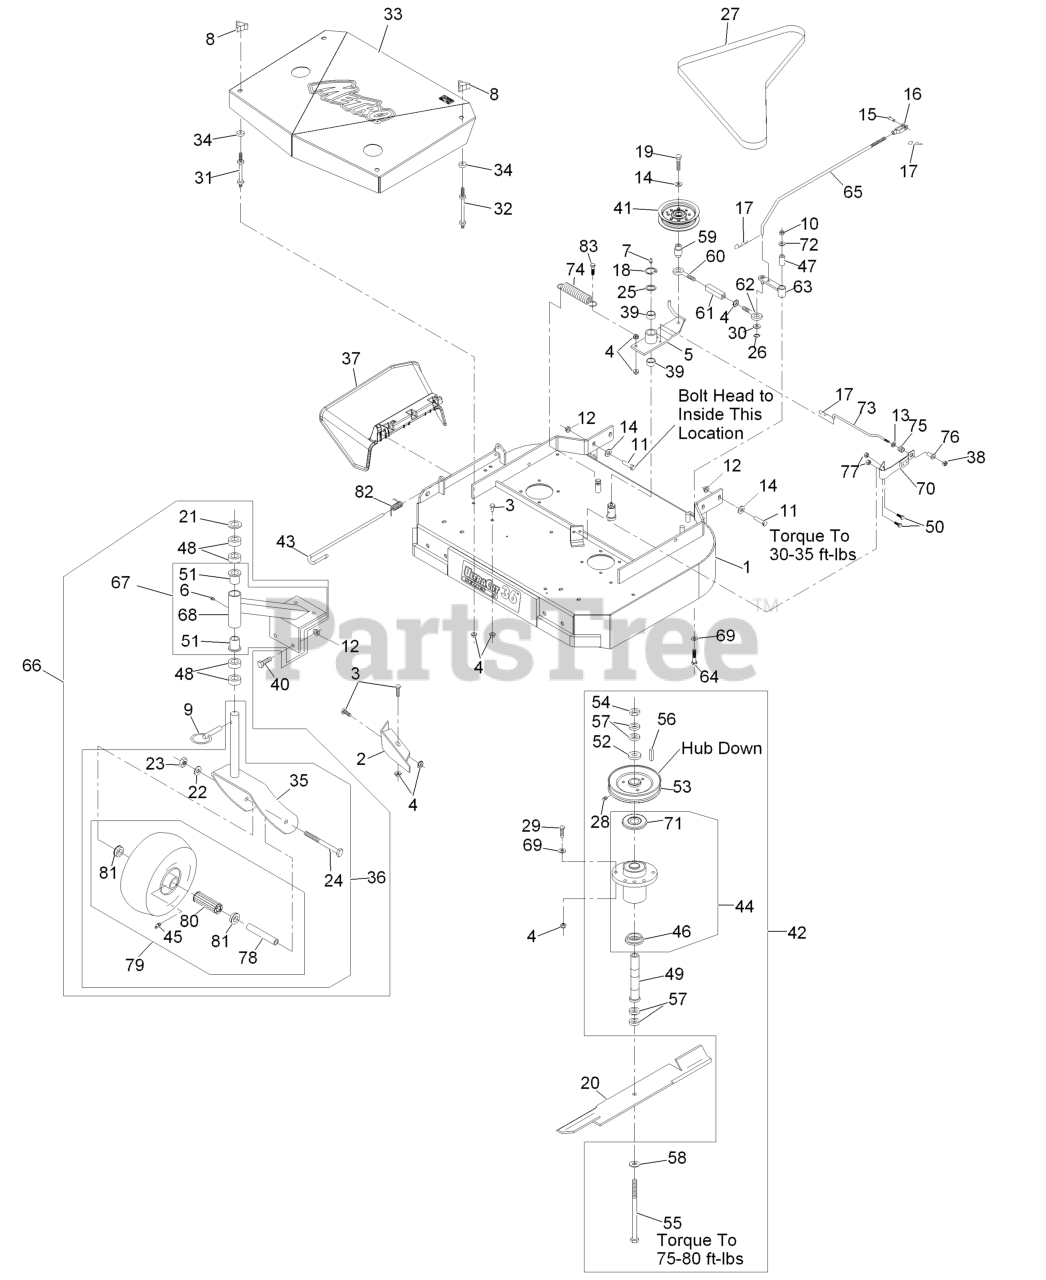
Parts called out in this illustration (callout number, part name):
1	ASM,DECK 36 RIGID
2	BAFFLE-DOGLEG
3	SCREW-HH
5	IDLER ARM ASM
6	FITTING-GREASE
7	FITTING-GREASE
8	KNOB-3 PRONG
10	NUT-LOCK, NI
11	SCREW-HH
12	NUT-HHF, WHIZ
13	RING-PUSH ON
14	WASHER-BELLEVILLE
15	PIN-CLEVIS
16	YOKE-ADJUSTABLE
17	PIN-COTTER
18	RING-RETAINING, EXT
19	SCREW-HH
21	WASHER-FLAT
22	WASHER-LOCK
23	NUT-HH
24	SCREW-HH
25	WASHER-SPINDLE
26	RING-RETAINING, EXT
27	BELT,BLADE METRO 36
28	SETSCREW
29	SCREW-HH
30	WASHER-PLAIN
31	STUD-SHIELD, BELT (SHORT)
32	STUD-SHIELD, BELT (LONG)
33	ASM,SHIELD W/DECALS 36 ME
36	ASM,CASTER/WHEEL
37	CHUTE DEFLECTOR XRK M056
38	NUT-LOCK, NI
39	SLEEVE-BEARING
40	SCREW-HH
42	ASM, CUTTER HOUSING OUTER
43	PIN-CHUTE
44	KIT, CUTTER HOUSING
45	FITTING-GREASE
46	SPACER-GUARD, BOTTOM
47	TUBE-PIVOT
48	SPACER-CASTER
49	TUBE-SPINDLE, SHORT
50	SCREW-HH
51	BEARING-FLANGED
52	WASHER-RETAINER, SHEAVE
54	NUT-HEX
55	SCREW-CAP, HH
58	WASHER-SPRING
59	BUSHING-ENGAGEMENT
60	EYEBOLT-THREAD, LH
61	BODY-TURNBUCKLE
62	EYEBOLT-THREAD, RH
63	ARM-ASSIST, 32/36
64	SCREW-HH
65	ARM-ASSIST, LINKAGE
66	ASM,CASTER/MOUNT
67	SUPPORT ASM
69	WASHER-SPRING
70	PAD AND SPRING ASM
71	GUARD-BEARING, TOP
72	WASHER-FLAT
73	ROD-BRAKE
74	SPRING-EXTENSION
75	SPRING-COMPRESSION
76	SPACER-FLANGED
77	NUT-LOCK, NI
79	KIT, SP CASTER WHEEL REPL
80	BEARING
81	BUSHING
82	SPRING, TORSION
83	SCREW-HH, SPECIAL
